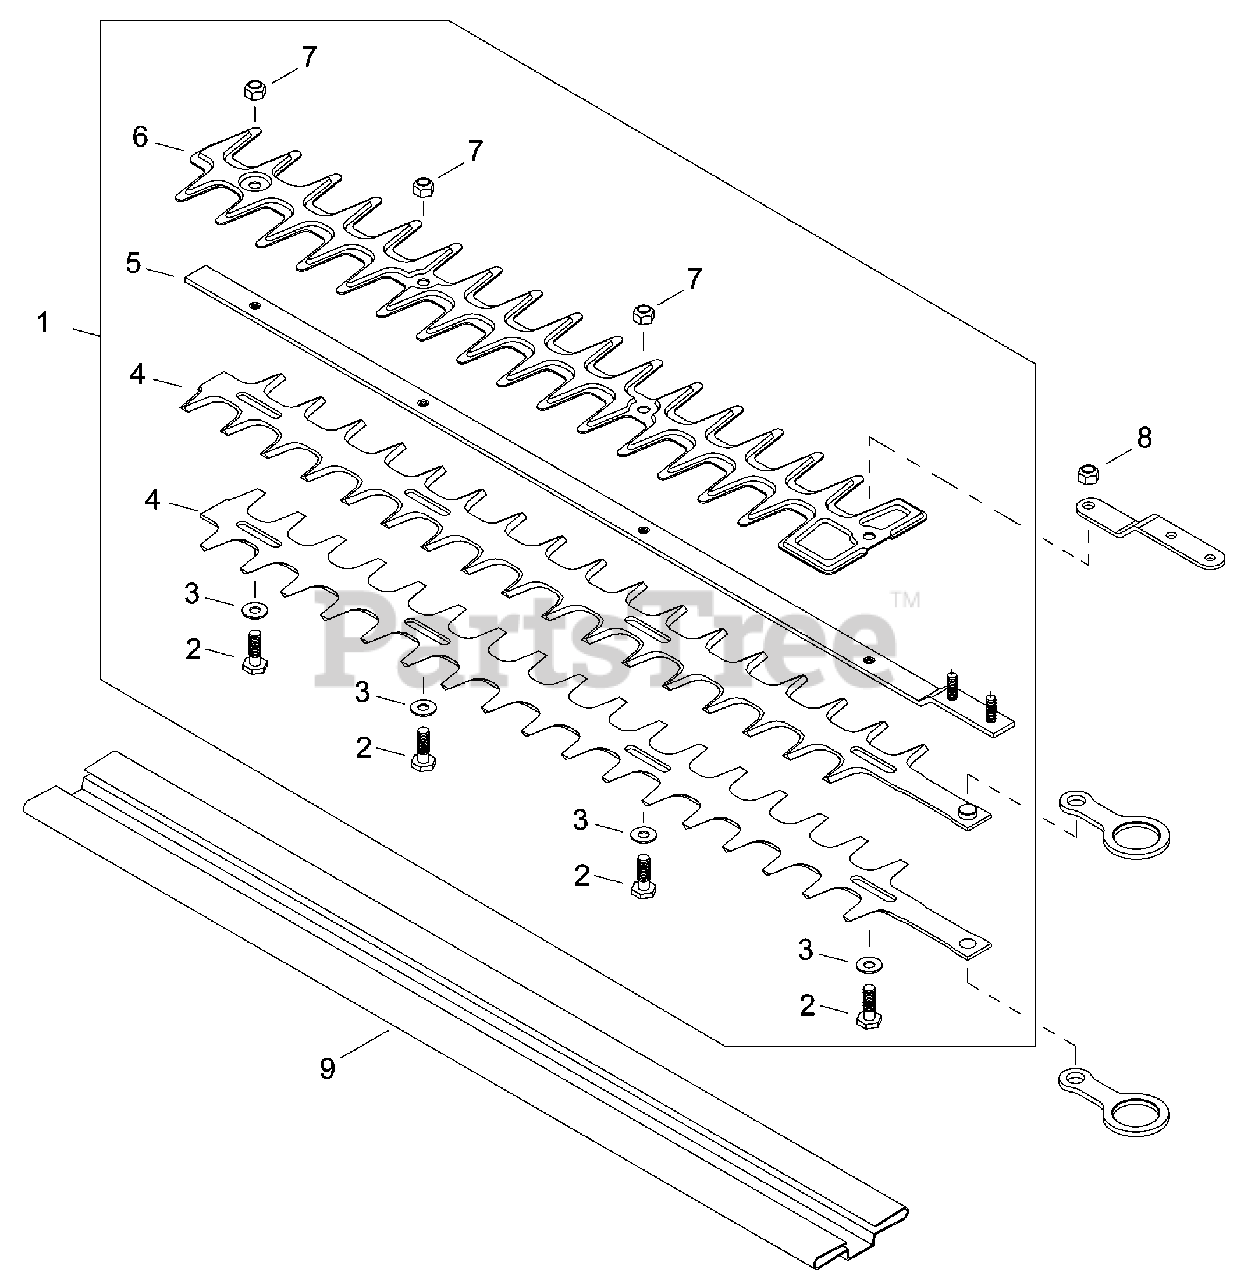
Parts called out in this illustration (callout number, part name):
1	BLADE KIT - 22" (55cm)
2	BOLT - 6X20
3	WASHER - 6
4	BLADE KIT - 22" (55cm) CHROME
5	GUIDE BAR - 22" (55cm)
6	GUARD, CUTTER BLADE
7	LOCKNUT - 6
8	LOCKNUT - 6
9	COVER, BLADE
